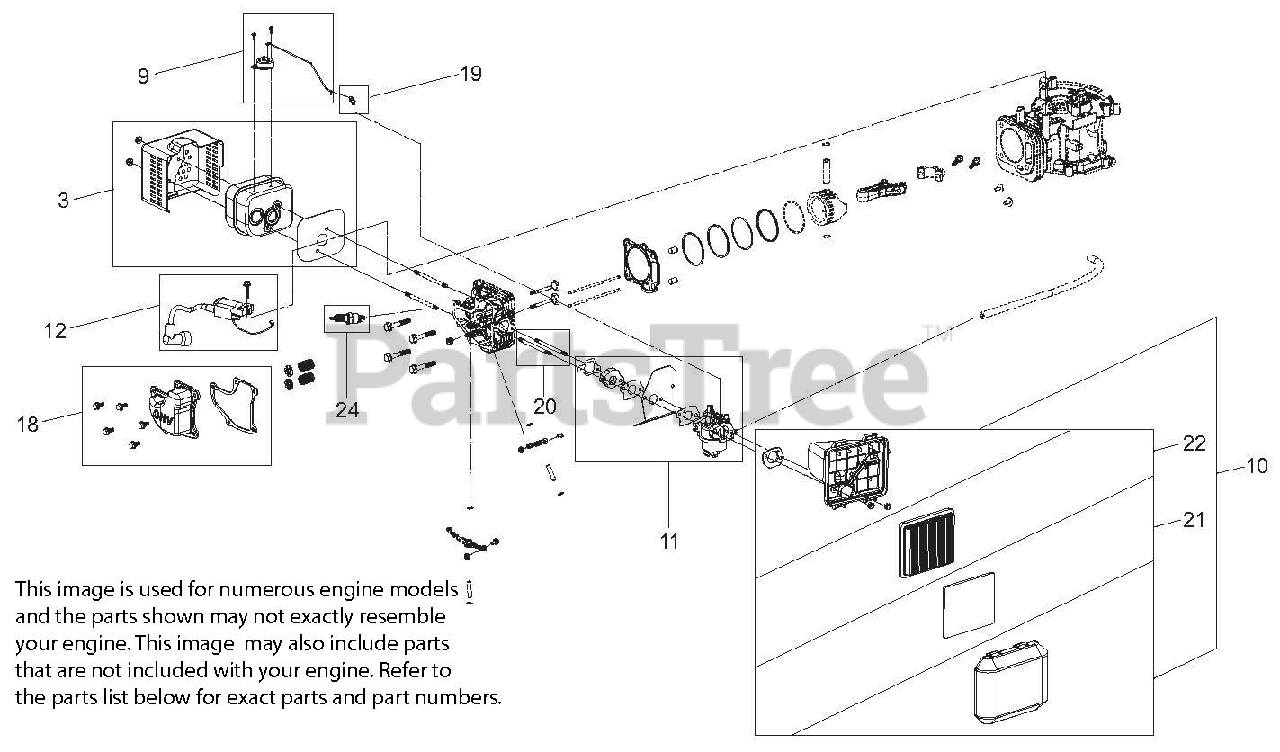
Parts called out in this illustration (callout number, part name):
3	KIT, MUFFLER AND SHIELD - SVC
9	KIT, THERMAL CHOKE CONTROL-SVC
10	KIT, AIR CLEANER ASM - SVC
11	KIT, CARBURETOR COMPLETE - SVC
12	KIT, IGNITION COIL - SVC
18	KIT, VALVE COVER - SVC
19	LOCK, THROTTLE - SVC
20	STUD, INTAKE - SVC
21	ELEMENT, AIR CLEANER
22	FILTER, AIR - LONCIN 160CC
24	SPARK PLUG, LONCIN 160CC
